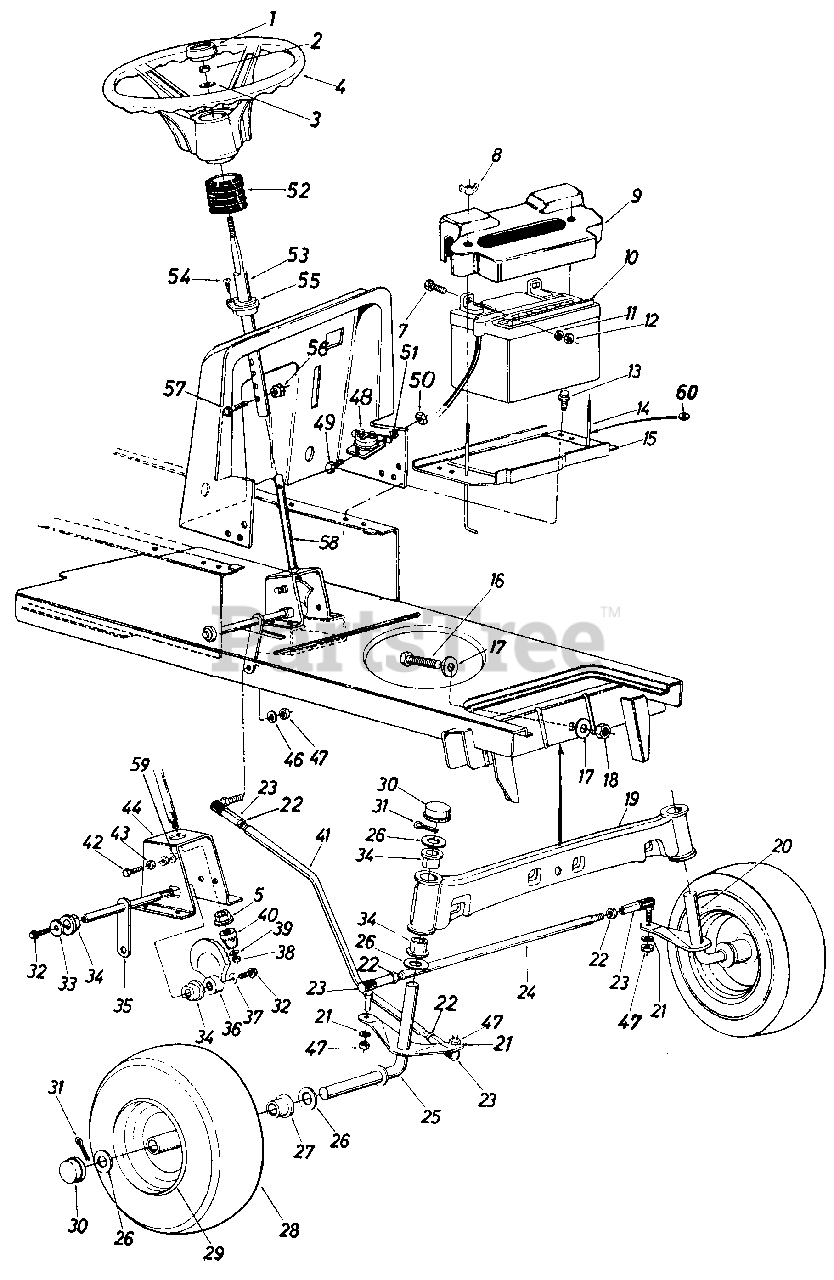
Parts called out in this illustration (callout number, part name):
1	Steering Wheel Cap
2	Hex Cent. L-Nut 5/16-24 Thd.
3	Bell-Wash. 5/16" I.D. x .87" O.D. x .060
4	Steering Wheel
5	Plastic Hex Bearing 5/8" I.D.
7	Hex Bolt 1/4-20 x .62" Lg.
8	Wing Nut Plastic 1/4-20 Thd.
9	Battery Cover
10	12-V Battery
11	L-Wash. 1/4" I.D.
12	Hex Nut 1/4-20 Thd.
13	Hex Thd. Rolling Scr. 1/4-20 x.50" Lg.
14	Battery Hold Down Rod
15	Battery Plate
16	Hex Bolt 5/8-18 x 2.5" Lg.
17	Flat Wash. .66" I.D. x 2.25" O.D. x .17
18	Hex Cent. L-Nut 5/8-18 Thd.
19	Front Pivot Bar Ass'y.
20	Front Axle Ass'y. L.H.
21	L-Wash. 3/8" I.D.
22	Hex Jam Nut 3/8-24 Thd.
23	Ball Joint Ass'y.
24	Tie Rod
25	Front Axle Ass'y. R.H.
26	Fl-Wash. .780 I.D. x 1.59 O.D.
27	Flange Bearing
28	Front Wheel Ass'y. Comp.
29	Front Wheel Rim Only
30	Dust Cover
31	Cotter Pin 5132" Dia. x 1.00" Lg.
32	Hex 8clt 3/8-24 x .75" Lg. Grade 5
33	Fl-Wash. 3/8 I.D. x 1.25 O.D. x .090
34	Flange Double "D" Brg. .753 I.D.
35	Steering Arm Shaft Ass'y.
36	Side Gear Steering
37	Bell-Wash. 3/8" I.D.
38	Hex Cent. L-Nut 5/16-24 Thd.
39	Fl-Wash. 5/16" I.D. x .62 O.D. x .059
40	Pinion Gear Steering
41	Drag Link
42	Hex Bolt 3/8-16 x 1.25" Lg.
43	Hex Nut 3/8-16 Thd.
44	Steering Gear Sup. Ass'y.
46	L-Wash. 3/8" I.D.
47	Hex Nut 3/8-24 Thd.
48	Solenoid
49	Hex Bolt 1/4-20 x .5" Lg.
50	Hex Sems Nut 1/4-20 Thd.
51	Ext. L-Wash. 1/4" I.D.
52	Steering Bellow
53	Upper Steering Shaft
54	Oval Hd. Cr.-Sunk Scr. #10 x 5/8" Lg.
55	Fl-Bearing .89" I.D. x 1.36" O.D.
56	Hex L-Nut 1/4-20 Thd.
57	Hex Bolt 1/4-20 x 1.25" Lg.
58	Lower Steering Shaft
59	Nylon Cap
60	Push Nut
